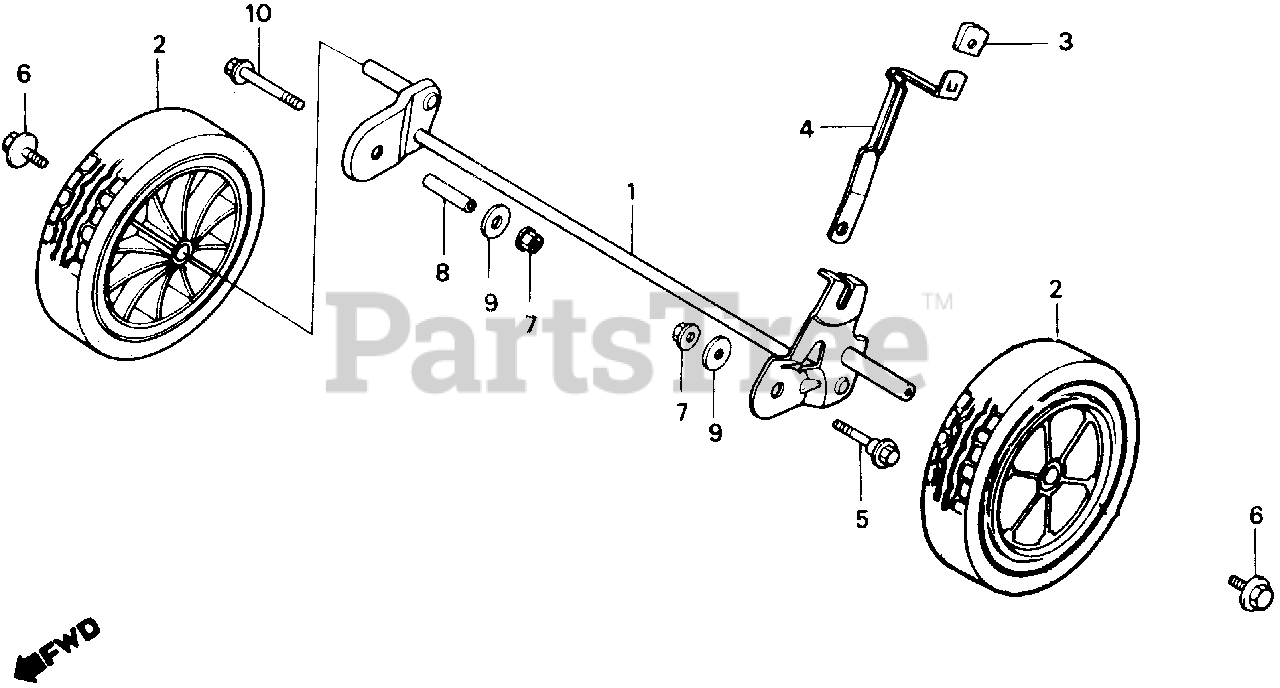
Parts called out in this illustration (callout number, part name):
1	SHAFT, RR. AXLE (NOT AVAILABLE)
2	WHEEL (7")
3	GRIP, ADJUSTER
4	PLATE, RR. ADJUSTING
5	BOLT, ADJUSTING CENTER
6	BOLT, WHEEL
7	NUT, FLANGE (8MM)
8	COLLAR A, ADJUSTING CENTER
9	WASHER, PLAIN (5MM)
10	BOLT, FLANGE (8X50)
